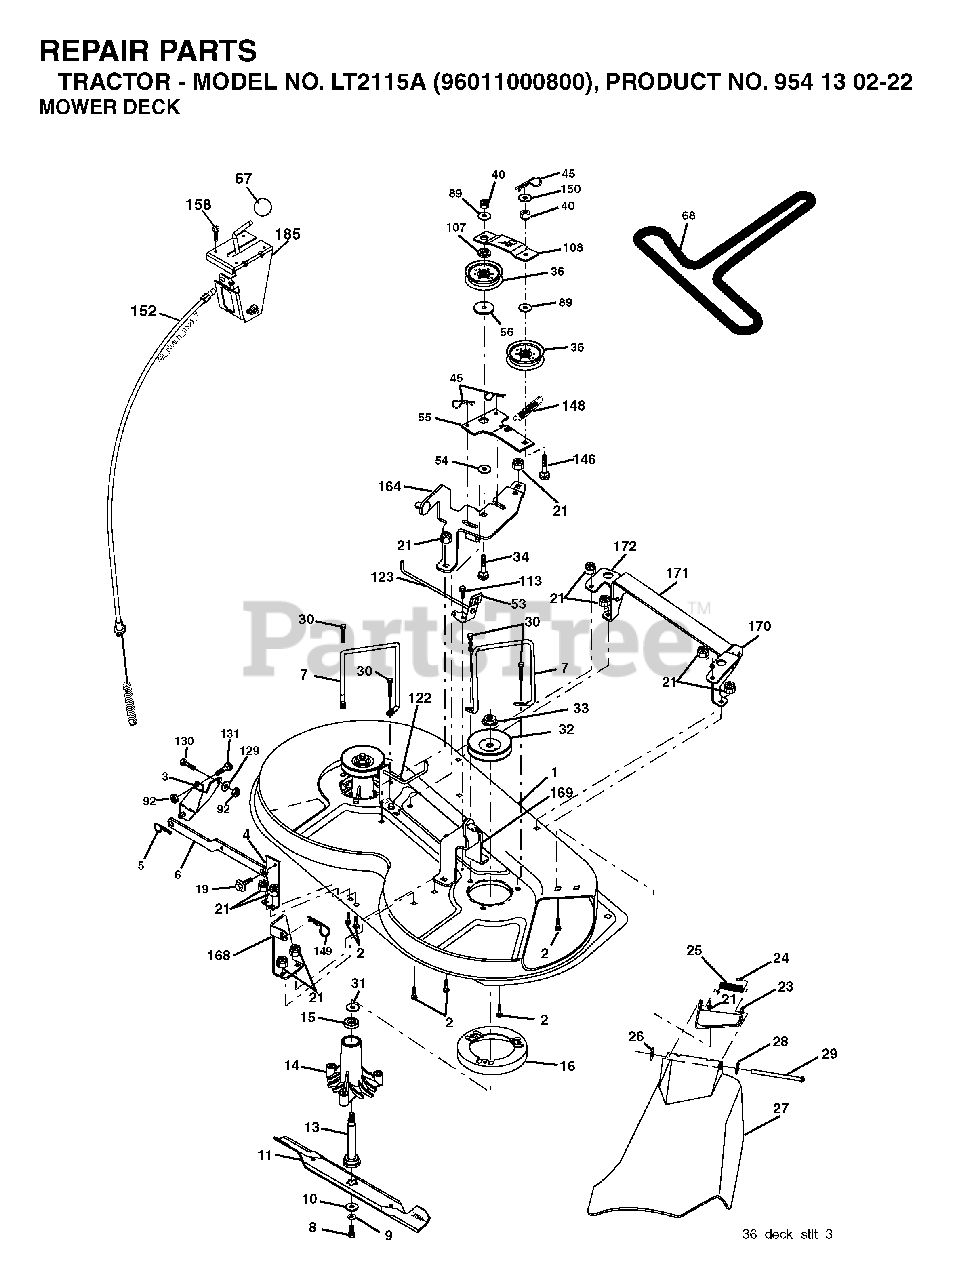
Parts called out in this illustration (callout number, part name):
2	BOLT
3	BRKT ASM SWAY BAR
5	RETAINER-SPRNG RB
6	BAR SWAY DECK
7	KEEPER LH
8	BLADE BOLT
9	LOCKWASHER
10	WASHER.BLADE
11	BLADE, HI-LIFT 36" PREMIUM
13	SHAFT ASM VENT
14	HSG MANDREL
16	STRIPPER, MWR ROUND
19	BOLT SHD 5/16-18
21	LOCKNUT
23	BRACKET ASM DEFLECTOR
24	CAP-SLEEVE LT
25	SPRING TORSION
26	NUT PUSH M
28	WASHER
29	HINGE ROD
30	SCREW, WASHER HEAD
31	WASHER.SPACER.MANDREL
32	PULLEY, MANDREL
33	NUT, FLG TOPLOCK 9/16"
34	BOLT
36	FLAT IDLER PULLEY
40	LOCKNUT
45	RETAINER M
53	BRAKE ASSEMBLY
55	IDLER ARM
56	SPACER.RETAINER.MOWER
67	KNOB T (3/8 HOLE)
68	V-BELT.MOWER.
89	WASHER
92	NUT
107	SPACER.IDLER.ARM
108	STIFFENER.IDLER.ARM
113	SCREW LT
129	WASHER
130	BOLT
131	BOLT D
146	BOLT, CARRIAGE IDLER
148	IDLER RETURN SPRING
149	SPRING.RETAINER.YELLOW.ZINC
150	WASHER LT
158	SCREW
171	BRACE
185	HEAD ASM. CABLE CLUTCH
